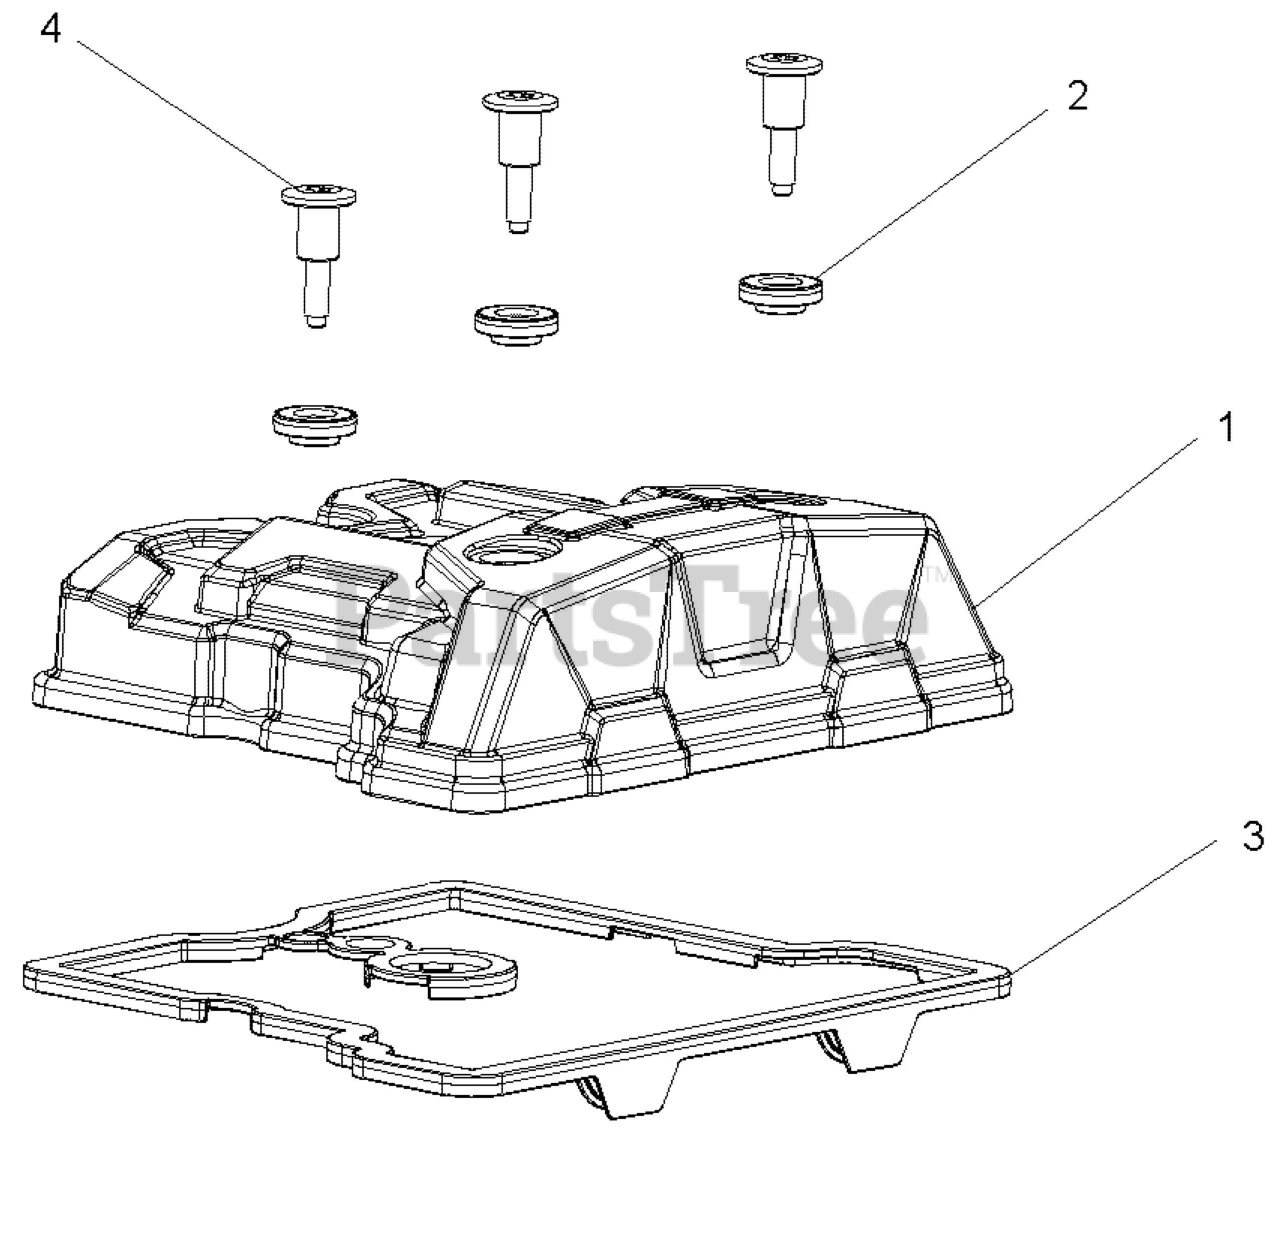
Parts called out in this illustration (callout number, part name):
1	COVER-VALVE,CAST,1CYL,DOHC
2	ISOLATOR-VALVE COVER
3	SEAL, VALVE COVER,1CYCL,DOHC
4	BOLT-SHLDR,M6X12X15
